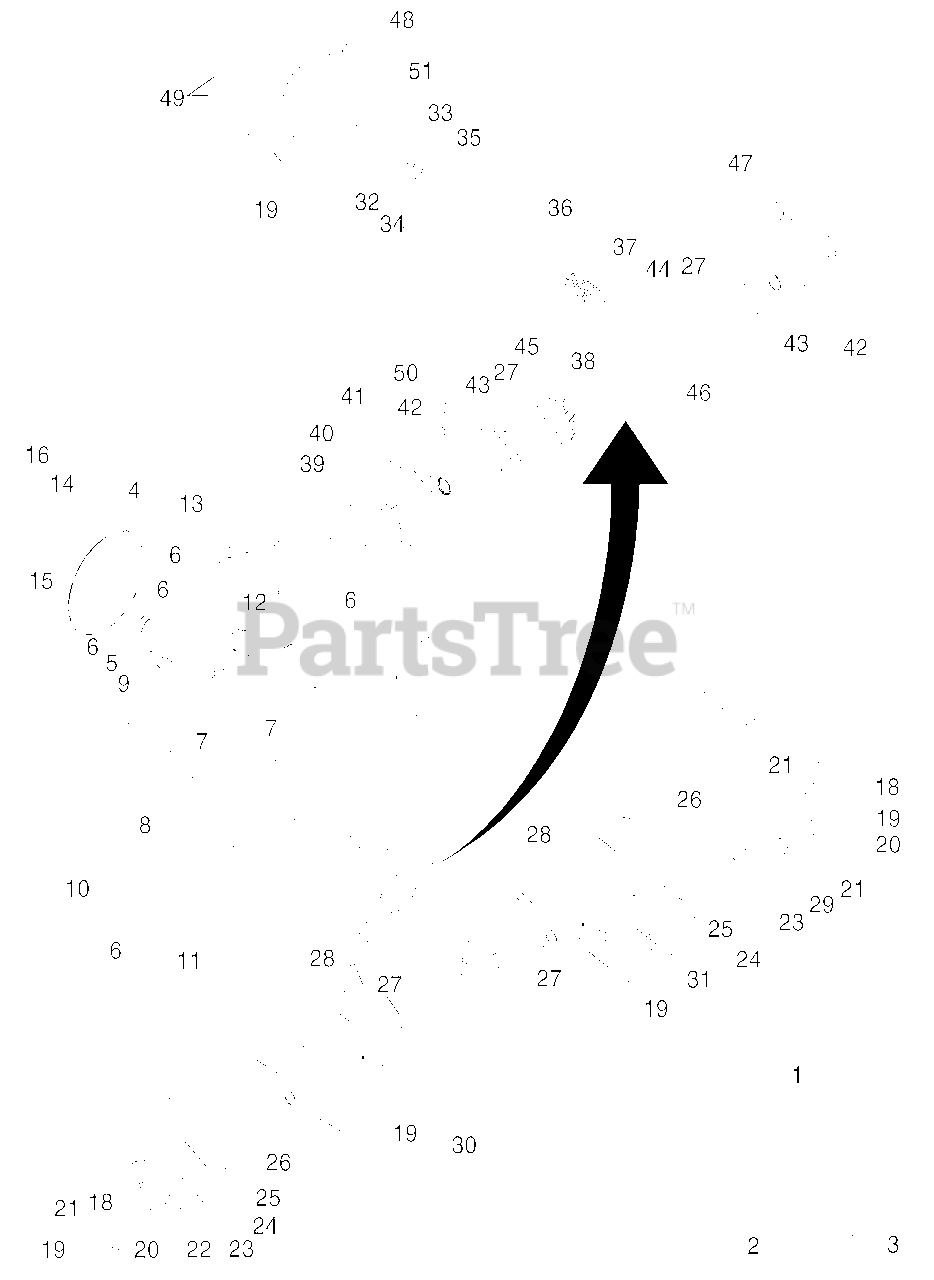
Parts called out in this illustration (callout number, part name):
1	Bag, Weight
2	Bracket, Weight Bag
3	Screw, Hex Head 5/16-18 x 1-1/2
4	Pulley, Impeller
5	Bearing Assembly, Flange
6	Nut, Hex Flange 5/16-18
7	Bolt, Flat Head, Carriage 5/16-18 x 5/8
8	Bolt, Carriage 5/16-18 x 5/8
9	Nut, Cage 3/8-16
10	Housing, Auger
11	Bar, Scraper
12	Bracket, Corner Discharge
13	Base, Discharge Chute
14	Washer, Flat
15	Washer, Lock 5/16
16	Screw, Hex Head 5/16-18 x 3/4
18	Screw, Hex Head 5/16 x 1
19	Nut, Hex Lock 1/4-20
20	Nut, Hex Lock 5/16-18
21	Washer, Flat
22	Skid Plate, RH
23	Washer, Nylon, Friction
24	Bolt, Carriage 5/16-18 x 3/4
25	Bolt, Shoulder
26	Bearing, Auger
27	Washer, Thrust, 1"
28	Bolt, Shoulder 1/4-20 x 2
29	Skid Plate, LH
30	Auger Assembly, RH
31	Auger Assembly, LH
33	Bushing, Flange 3/4
34	Washer, Thrust 3/4
35	Bearing, Thrust 3/4
36	Shaft, Impeller
37	Washer, Thrust 5/8
38	Bushing, Flange 5/8
39	Screw, Hex Head 5/16-18 x 3/4
40	Plug, Case
41	Housing, Gearbox, RH
43	Bushing, Flange, 1"
44	Key, Square 1/4 x 1/4 x 7/8
45	Gear, Worm
46	Shaft, Auger
47	Housing, Gearbox, LH
48	Impeller Assembly
49	Screw, Hex Head 1/4-20 x 1-5/8
50	Gasket, Gearbox
51	Pin, Roll 3/16 x 1-1/8
